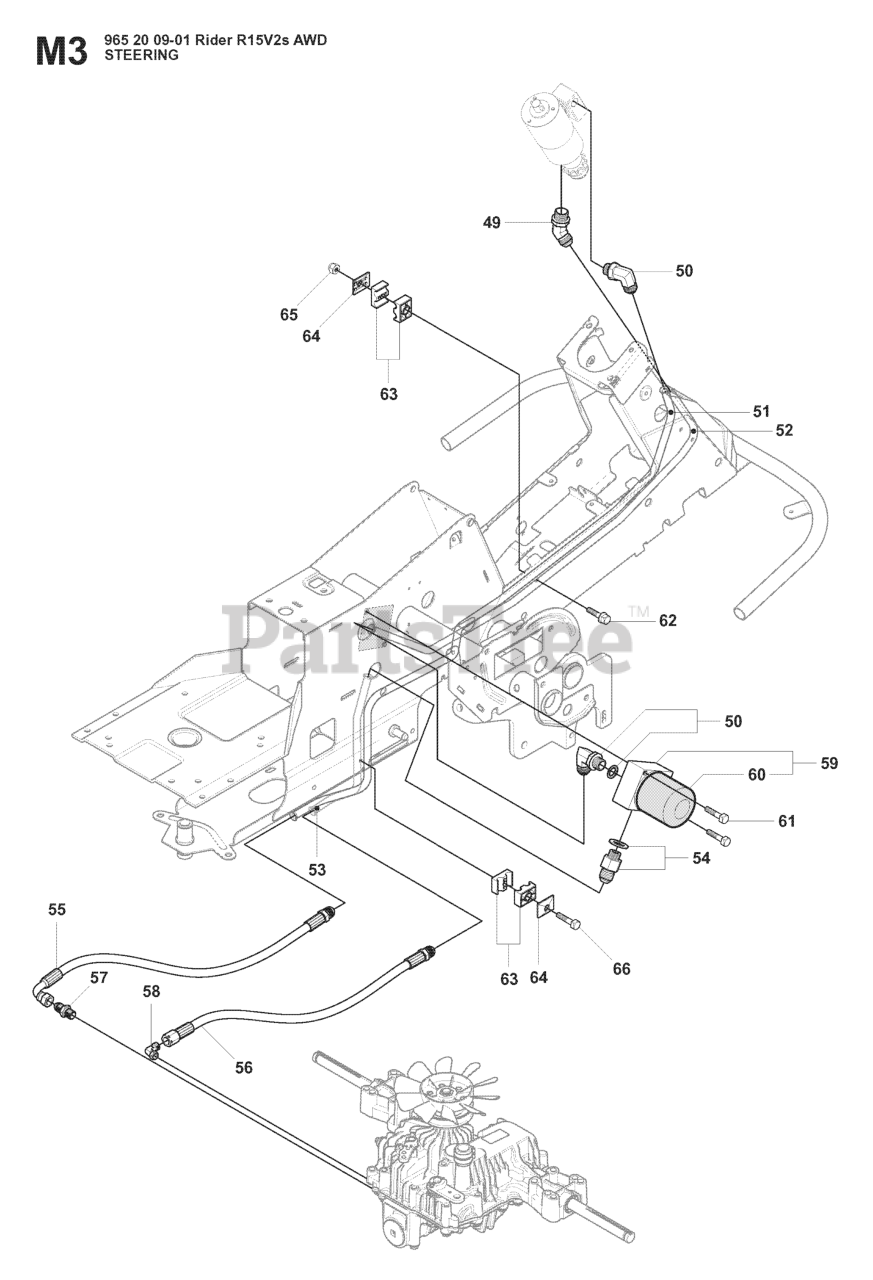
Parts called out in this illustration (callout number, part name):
48	COMFORT STEERING
60	FILTER
63	PIPE CLAMP
65	LOCKNUT M6
